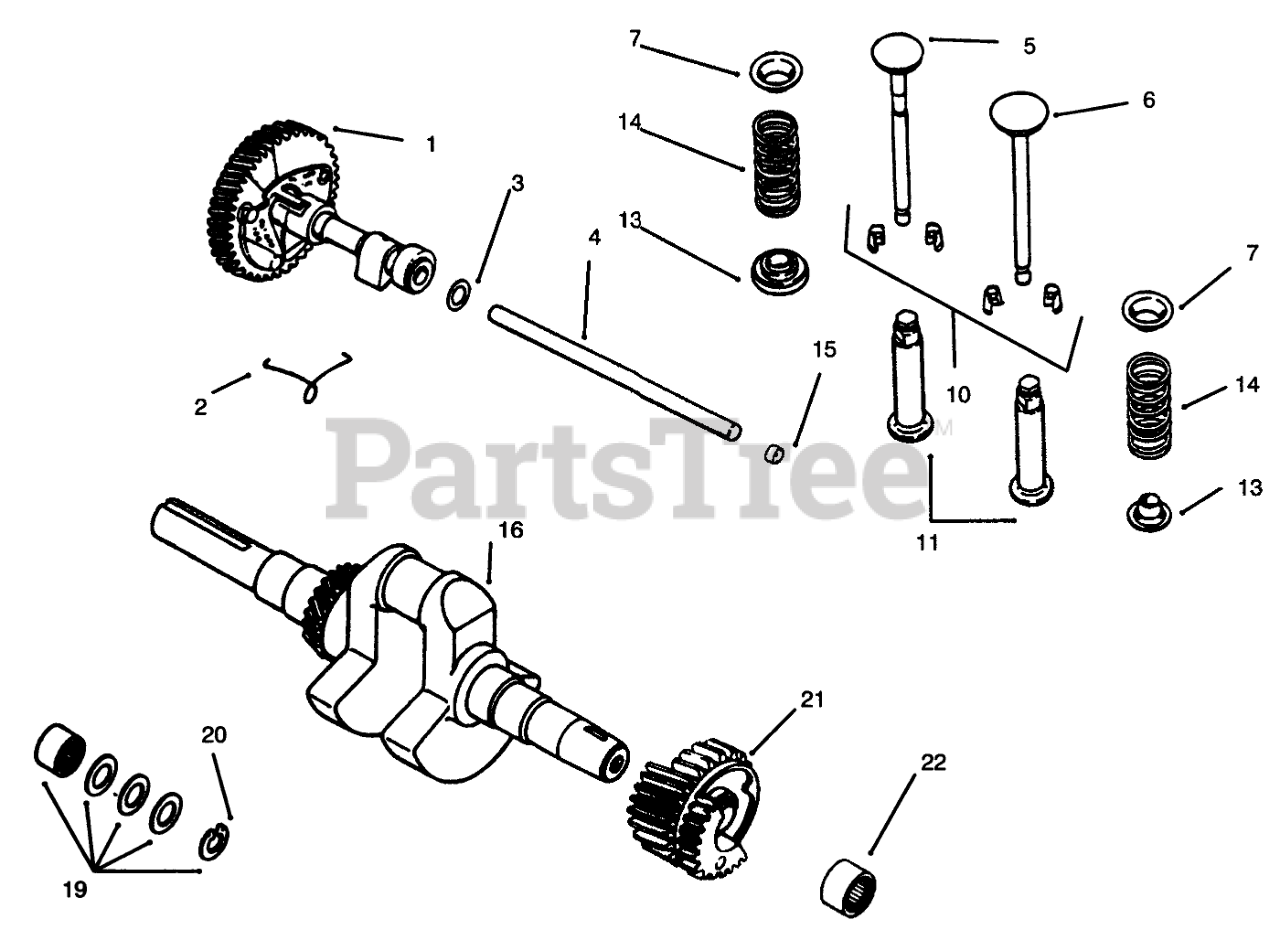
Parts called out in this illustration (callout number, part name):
1	Camshaft ASM INC 2
2	Spring
3	Spacer
4	Pin-Camshaft
5	Valve-Exhaust
6	Valve-Intake
7	Retainer-Spring
8	Spring
10	Kit-Retainer
12	Tappet
13	Retainer-Spring
14	Spring
14	Rotator-Valve
15	Plug
16	Kit-Crankshaft
19	Kit-Spacer
20	Retainer
